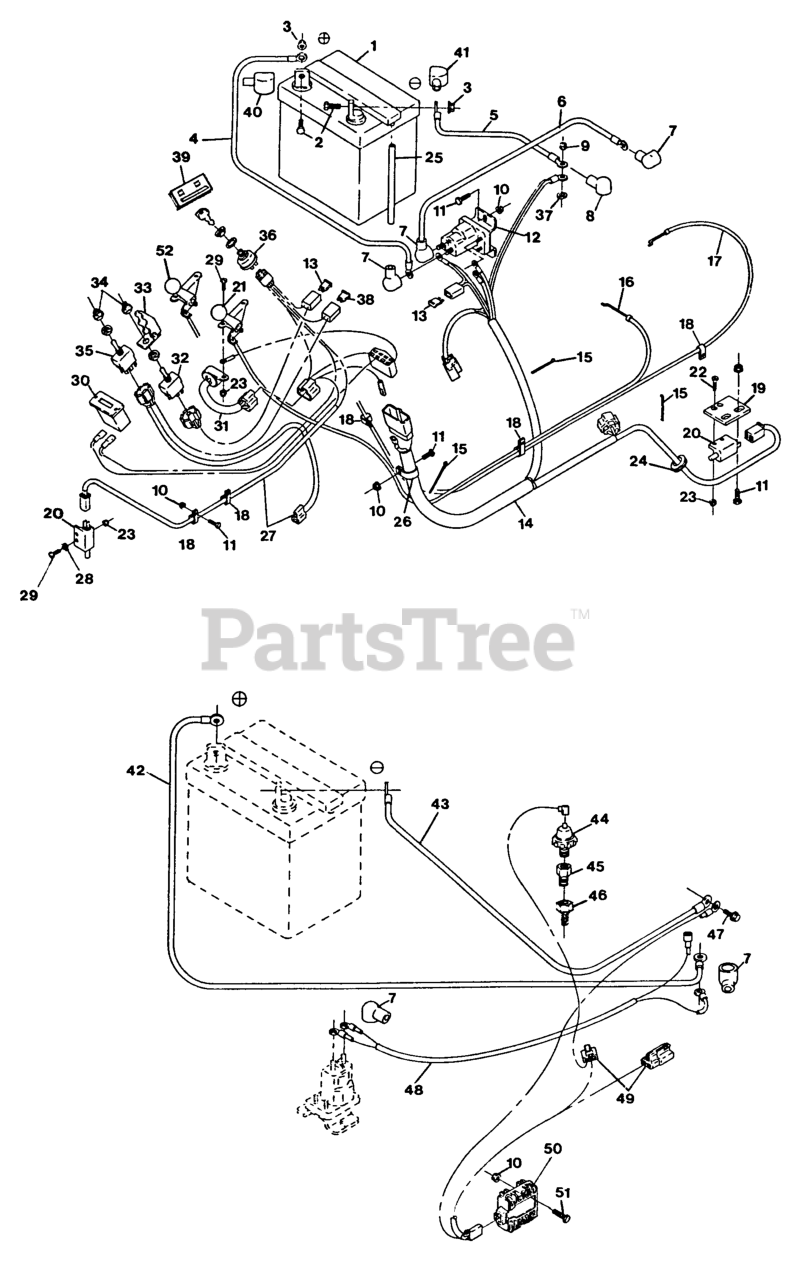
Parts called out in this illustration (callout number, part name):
1	Battery, 12v Manifold
4	WIRE,BATTERY POSITIVE
7	INSULATOR-SOLENOID
13	FUSE-BLADE TYPE, 20 AMP
15	TIE-CABLE
19	BRACKET,SAFETY SWITCH
20	SWITCH-OPEN, NORMALLY
21	KNOB-BALL
24	GROMMET
26	CLIP-LOOM
30	METER-HOUR
34	BOOT-SWITCH, TOGGLE
35	SWITCH-TOGGLE, DPDT
38	FUSE-BLADE TYPE, 30 AMP
41	INSULATOR, BATTERY -
43	WIRE-GROUND
44	SWITCH-OIL PRESSURE
47	M8 X 1.25 X 16 Mm Hh Capscrew
50	Voltage Regulator
52	KNOB-BALL, BLACK
